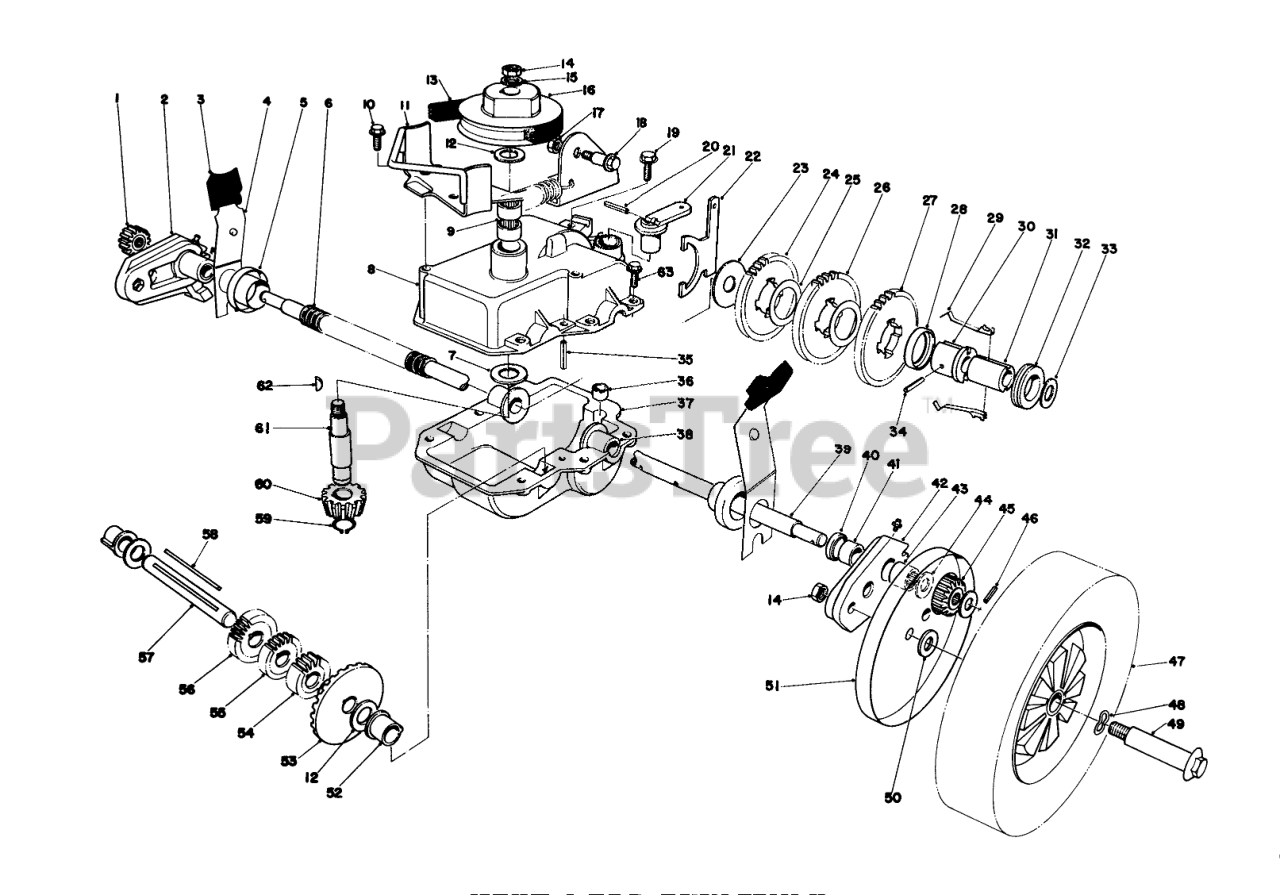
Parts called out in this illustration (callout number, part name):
1	RH CLUTCH & PINION
2	Pivot Arm R.H. (Incl. Ref. #40, 41 & 43)
3	KNOB-ARM
4	Spring Arm
5	End Cap
6	CONDUIT-CONVOLUTED, SPLIT
7	Thrust Washer
8	Upper Gear Case
9	Bearing
10	Screw
11	Belt Guide Bracket
12	WASHER-THRUST
13	V-BELT
14	Nut
15	WASHER-FLAT
16	PULLEY
17	NUT-HEX, SIDE DEFORM
18	Shoulder Bolt
19	SCREW-HWHTF
20	PIN-COIL
21	LEVER-SHIFT
22	Shift Yoke
23	WASHER
24	Gear 38T
25	WASHER
26	Gear
27	Gear
28	KEY RETAINER
29	KEY-SHIFT
30	Body-Sleeve
31	SLEEVE
32	COLLAR-SHIFT
33	WASHER-PLAIN
34	COIL PIN
35	ROLL PIN 3/16 X 1 IN
36	BUSHING-YOKE
37	LOWER GEAR CASE CAST
38	Bushing
39	OUTPUT SHAFT
40	Seal
41	Bushing
42	Pivot Arm L.H. (Incl. Ref. #40, 41 & 43)
43	Needle Baring
44	WASHER
45	LH CLUTCH & PINION
46	Pin
47	Wheel & Tire Assembly
48	SPRING WASHER
49	BOLT-WHEEL
50	WASHER
51	Cover-Wheel
52	Botching Shaft
53	BEVEL GEAR
54	14 T GEAR
55	16 T GEAR
56	GEAR-18T
57	Sort Shaft
58	Key Square
59	RING-RETAINING
60	PINION-BEVEL
61	Input Shaft & Pinion Assembly (Incl. Ref. #59)
62	KEY-WOODRUFF
63	SCREW-HWH, THREAD ROLL
